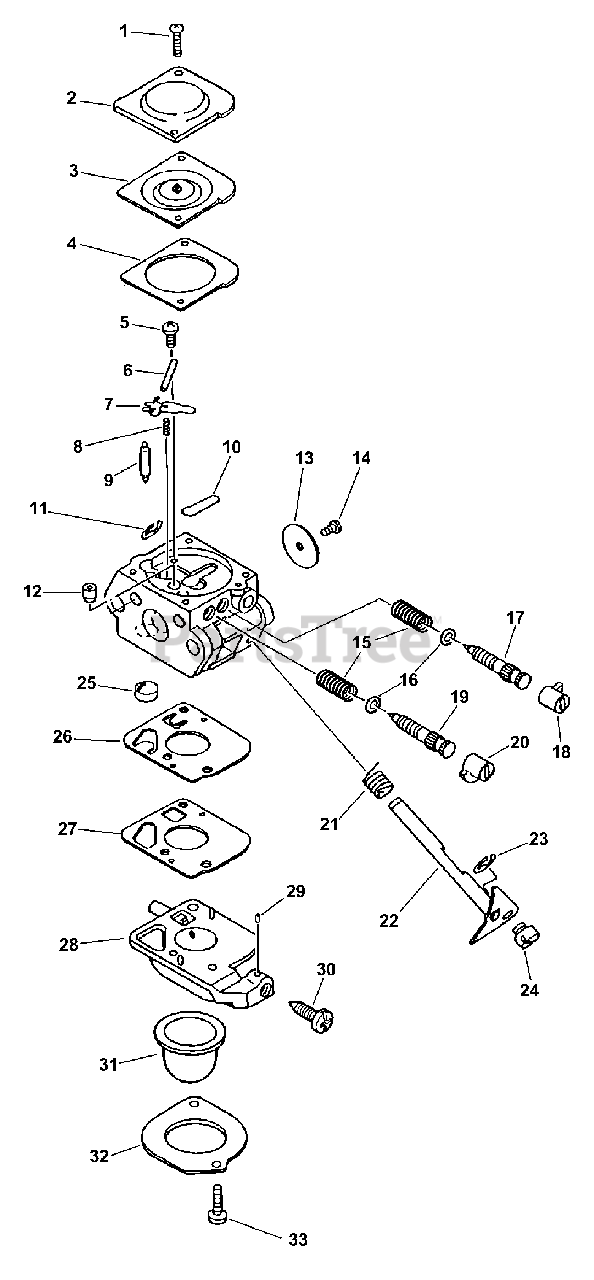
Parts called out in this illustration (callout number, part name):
1	SCREW
2	COVER, METERING DIAPHRAGM
3	DIAPHRAGM, METERING
4	GASKET, METERING
5	SCREW
6	PIN, METERING LEVER
7	LEVER, METERING
8	SPRING, METERING LEVER
9	VALVE, INLET NEEDLE
10	PLUG, WELCH
11	E-RING
12	NOZZLE, CHECK VALVE
13	VALVE, THROTTLE
14	SCREW
15	SPRING, NEEDLE
16	WASHER
17	NEEDLE, IDLE
18	CAP, LIMITER - WHITE
19	NEEDLE, HIGH SPEED
20	CAP, LIMITER - RED
21	SPRING, THROTTLE RETURN
22	SHAFT, THROTTLE
23	CLIP
24	SWIVEL
25	STRAINER
26	DIAPHRAGM, PUMP
27	GASKET, PUMP
28	BODY ASSY, PURGE
29	PIECE, FRICTION
30	SCREW, IDLE ADJUST
31	BULB, PURGE
32	RETAINER
33	SCREW
